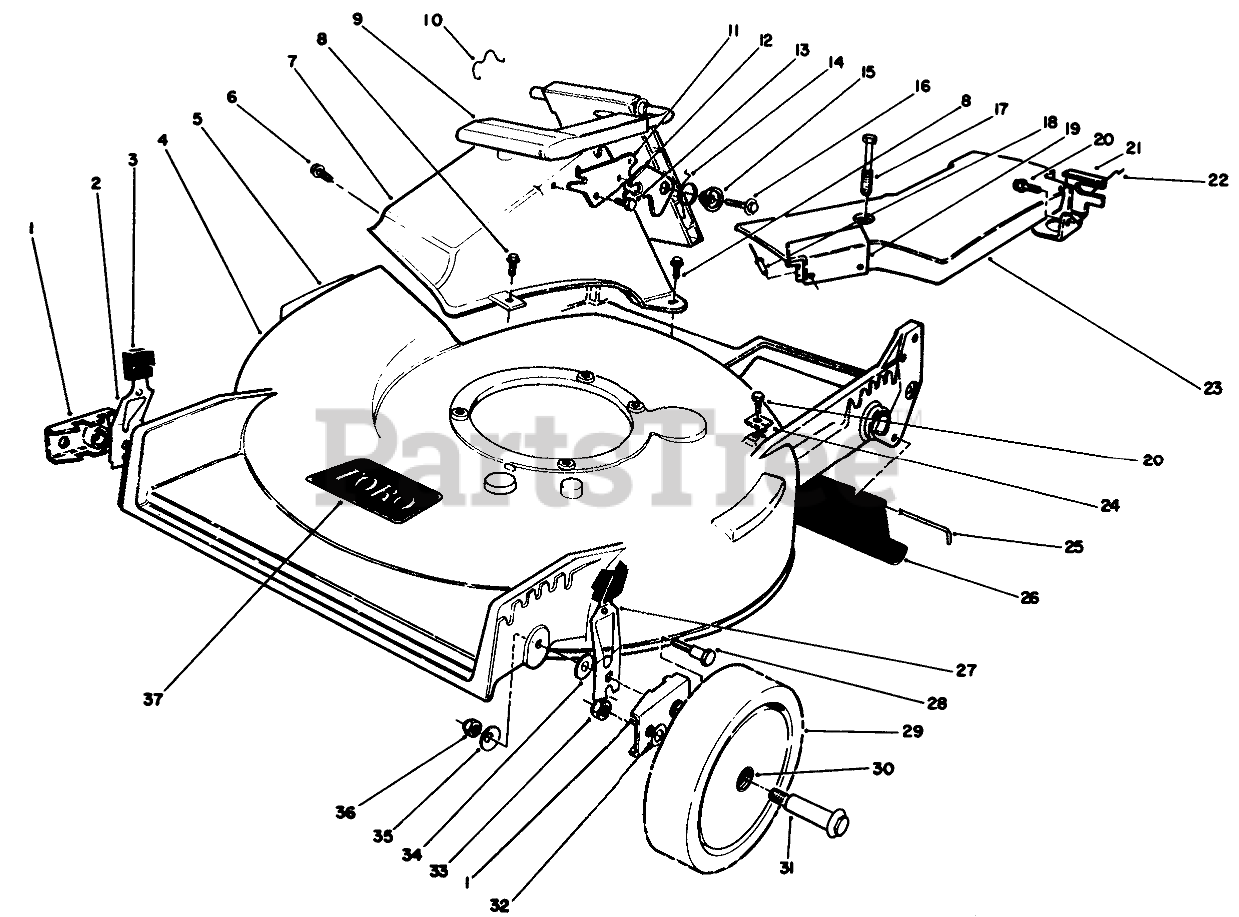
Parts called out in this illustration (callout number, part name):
1	HP PIVOT ARM ASM
2	R HP SPRING ARM ASM
3	KNOB-ARM
4	Housing (Incl. Ref. #5)
5	DECAL-DANGER
6	SCREW AND WASHER ASM
7	Tunnel Discharge
8	SCREW-HWH
9	Discharge Door Assembly
10	DOOR RET SPRING
11	DOOR LATCH PLATE
12	SAFETY LATCH
13	SCREW-PLASTITE
14	Spring-Torsion
15	DOOR SPACER
16	SCREW-HWH
17	SCREW-HHFTF
18	RIVET-HEAD, FLAT
19	HEAT SHIELD
20	SCREW-HWHTF
21	Bracket-Traction Adj.
22	RETAINER-CABLE
23	Belt Cover Assembly (Incl. Ref. #18 & 19)
24	CLAMP-CABLE
25	ROD-SHIELD
26	SHIELD - TRAILING
27	L. HP SPRING ARM ASM
28	PIVOT SCREW
29	Wheel & Tire Assembly (Incl. Ref. #30)
30	BUSHING
31	WHEEL BOLT
32	WASHER
33	Nut
34	WASHER-PIVOT
35	WASHER-BELLEVILLE
36	NUT-LOCK, NI
37	DECAL
